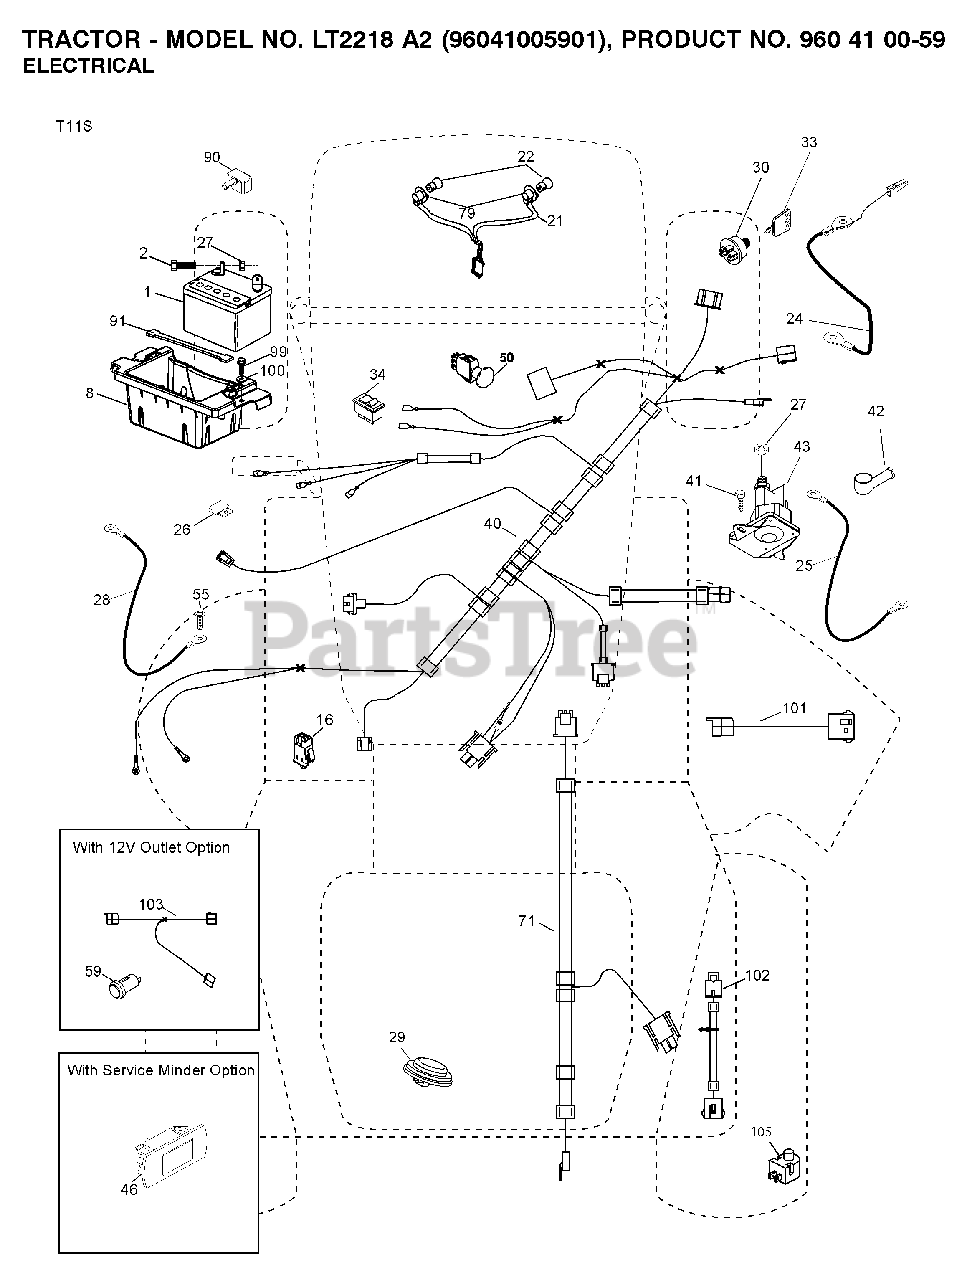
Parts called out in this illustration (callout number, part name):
1	BATTERY 12V .35 AMP
8	BOX.BATTERY.MOUNT.FRONT.LT
16	SWITCH INTERLOOK PUSH-IN
21	HARNESS.W/LIGHT SOCKET
22	LIGHTBULB
24	CABLE.BATT.POS.WIRE.TG.DA SOL
25	CABLE.START.RED.17.5".
26	FUSE 20AMP
27	NUT
28	CABLE GROUND 6 GA 21" 90T BLK
29	SWITCH.SEAT.DELTA.OPC.
30	SWITCH.IGN.DELTA.W.LGH.ROS
33	KEY.CHAIN.BLISTER.PACK.GEN.USA
34	SWITCH LT
40	HARNESS.IGN.DASH.HUQ/P
41	SCREW
42	TERMINAL COVER
43	SOLENOID.W/BRASS.PLUNG
46	GUAGE.SRVCMNDR.HRMTR.
50	PTO SWITCH
55	SCREW 5/16"
71	HARNESS-CHASSIS SUB
79	BULB HOLDER ASM.
90	COVER.TERMINAL.BATTERY
91	STRAP, BATTERY MOUNT
99	SCREW HEXWSHR 1/4-20X3/4
101	PIGTAIL.MATNLK.NEW.HAR
102	HARNESS PIGTAIL PCH TEX ROS
105	REVERSE SWITCH
